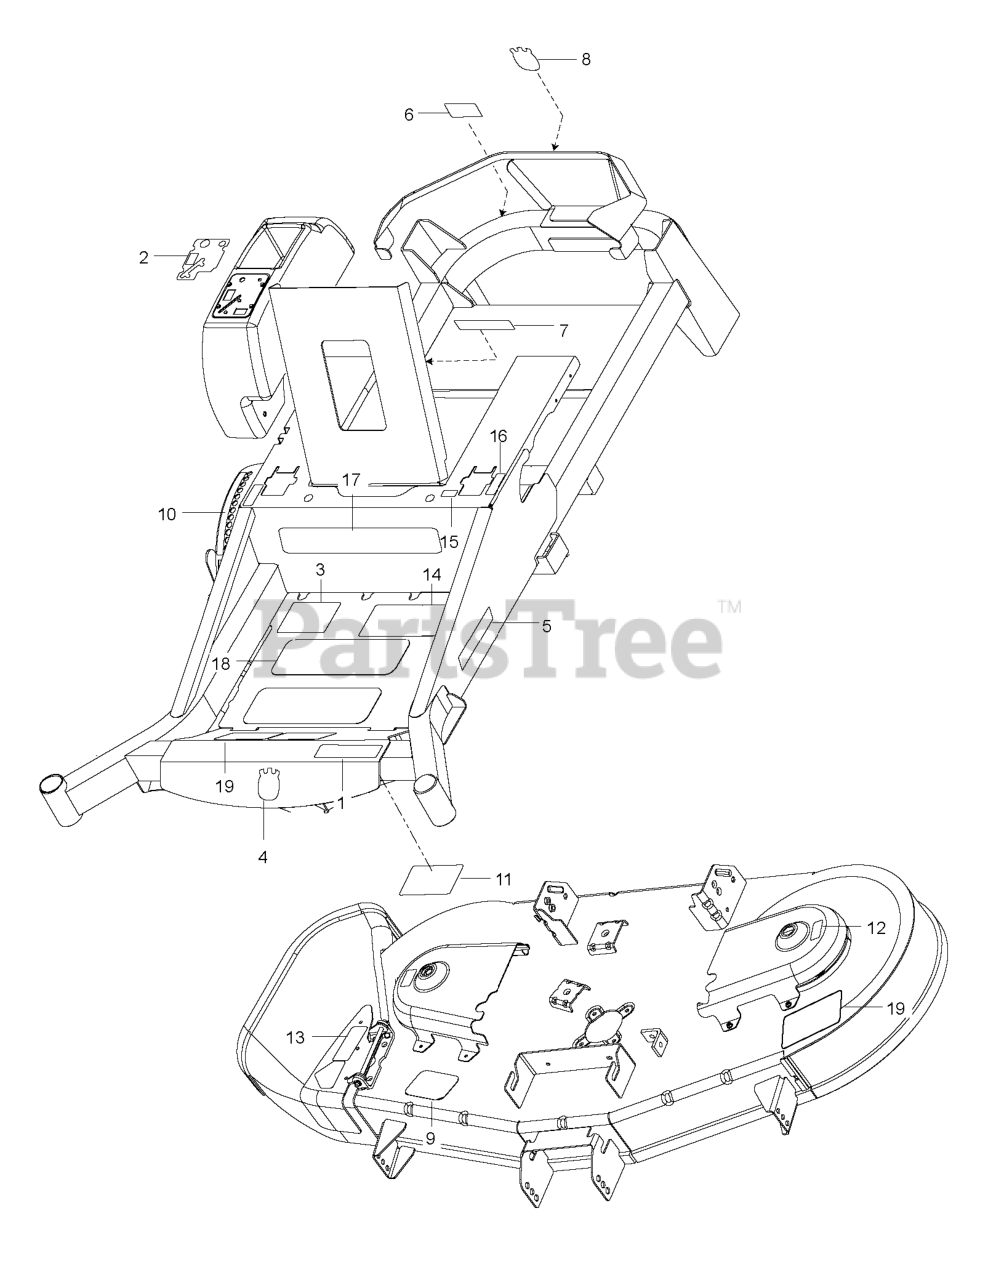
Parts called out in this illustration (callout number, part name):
1	DECAL ZTR MODEL NUMBER DECAL.Z
2	DECAL, CONSOLE HUS
3	DECAL.ZTR.STRTNGINST.REMOTECHK
4	DECAL.AUGER.HUSQ.CROWN.SNOW
5	RP.DECAL.BADGE.170MM.TEXTLOGO
6	DECAL, BELT DRIVE
7	EURO DECAL-BATTERY WARNIN6
8	DECAL, CROWN H, 110MM
9	DECAL BELT ROUTING DECAL DECAL
10	DECAL, HEIGHT ADJUST
11	DECAL, SERVICE
12	DECAL.DECK.CLEARCUT.NOSTEP
13	DECAL.TRACT/ZTR.DECKWARN.HUSQ
14	DECAL ZTR WARNING DECAL DECAL.
15	DECAL.STR.S.T.SYSMBOLONLY.2014
16	DECAL.ZTR.MOTCONTRL.SYMBOL.HUS
17	DECAL ZTR BRAND GRAPHIC DECAL.
18	ANTI-SKID PAD
